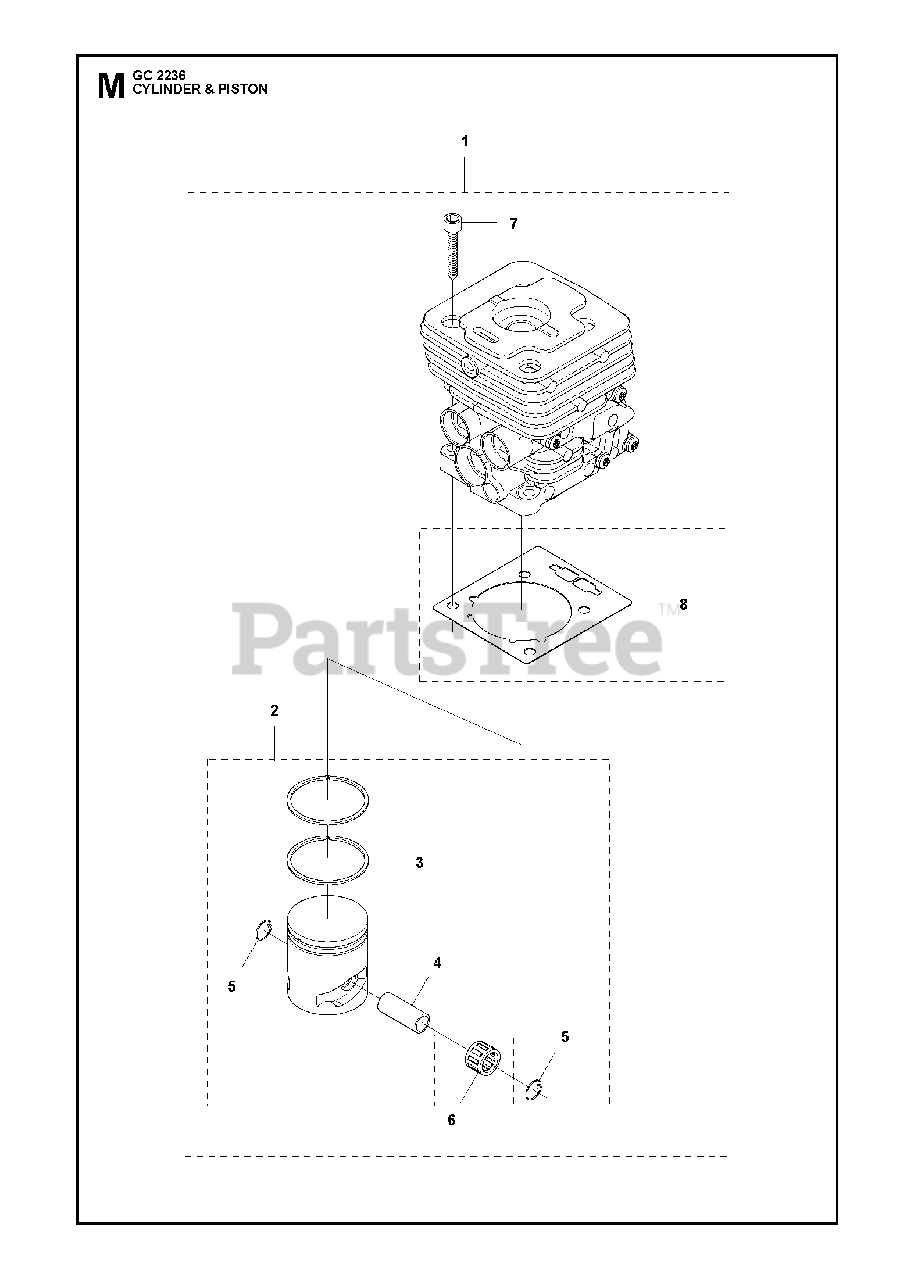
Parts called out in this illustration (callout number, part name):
1	%CYLINDER CPL
2	PISTON CPL
3	PISTON RING
4	PISTON BOLT
5	LOCKING RING
6	SUPPORT BUSHING
7	SCREW
8	GASKET CYLINDER
